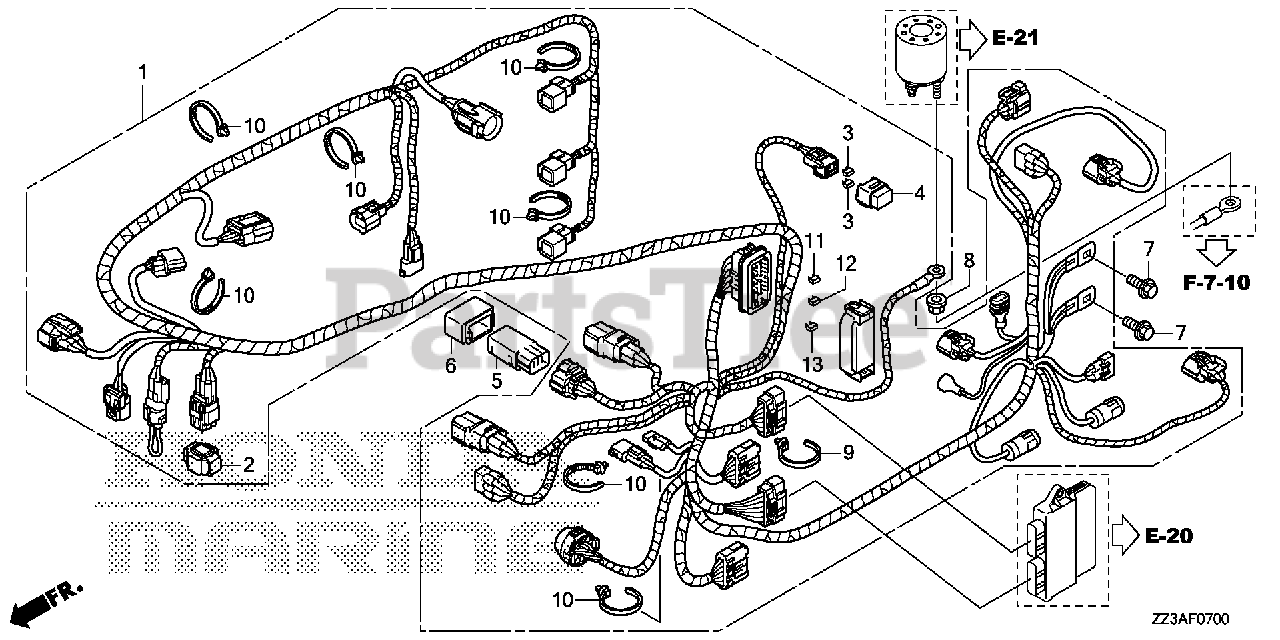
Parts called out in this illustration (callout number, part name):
1	WIRE HARNESS ASSY., MAIN
2	SUSPENSION, CONNECTOR
3	FUSE, BLADE (40A)
4	COVER ASSY., FUSE (40A)
5	RELAY ASSY., MAIN
6	SUSPENSION, RELAY
7	BOLT, FLANGE (6X12)
8	NUT-WASHER (8MM)
9	CLIP, WIRE HARNESS (110MM) (7MM HOLE) (GREEN)
10	CLIP, HARNESS BAND (145MM) (BLACK)
11	FUSE, MINI (10A)
12	FUSE, MINI (15A)
13	FUSE, MINI (30A)
